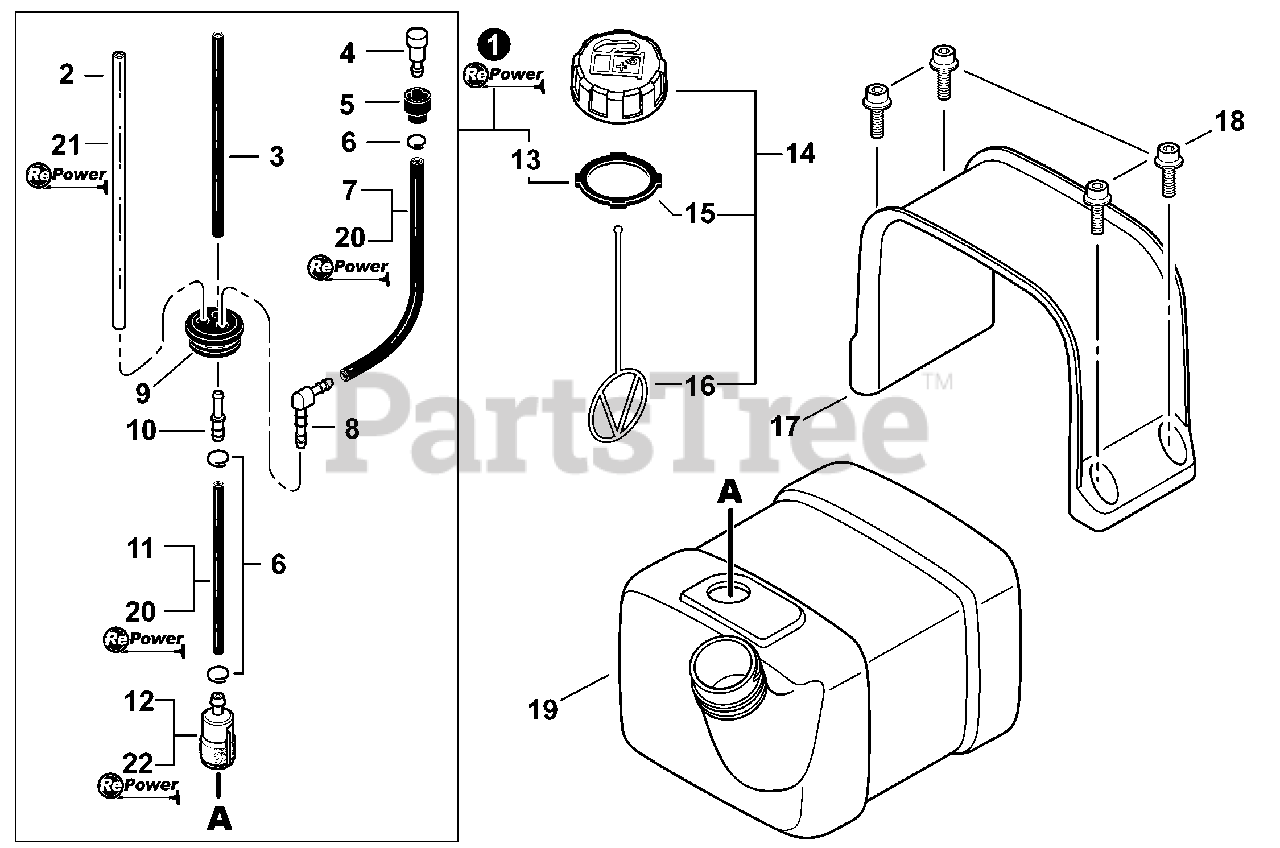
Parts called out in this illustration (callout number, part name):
1	FUEL SYSTEM KIT - REPOWER
2	PIPE, FUEL RETURN 3×6×145
3	PIPE, FUEL 3×5×110
4	VENT ASSY
5	HOLDER, VENT
6	CLIP 6.5MM
7	PIPE, VENT 3×6×145mm
8	CONNECTOR, PIPE 5.4
9	GROMMET, FUEL
10	CONNECTOR, PIPE 5×3.5
11	PIPE, FUEL 3×6×120
12	FILTER, FUEL
13	GASKET, FUEL CAP
14	CAP ASSY, FUEL
15	GASKET, FUEL CAP
16	CONNECTOR, CAP L= 100mm
17	BRACKET, FUEL TANK
18	BOLT 5×16
19	TANK, FUEL
20	PIPE, BULK - REPOWER 3×6mm BLACK
21	PIPE, BULK - REPOWER 3×6mm CLEAR
22	TUNE-UP KIT - REPOWER
